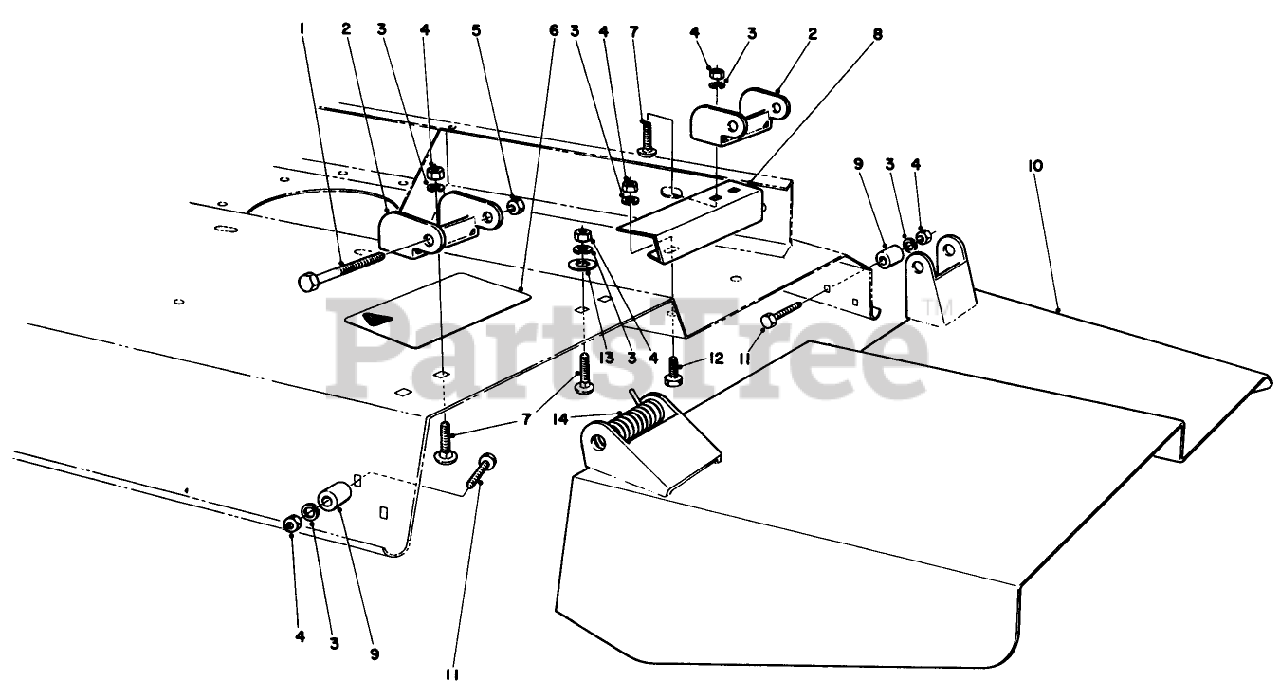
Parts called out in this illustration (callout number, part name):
1	SCREW-HH
3	WASHER-LOCK
4	NUT-HEX
5	NUT-HEX
6	WARNING DECAL
7	SCREW-CARR
11	SCREW-HH
12	SCREW-HH
13	WASHER-FLAT
14	SPRING
